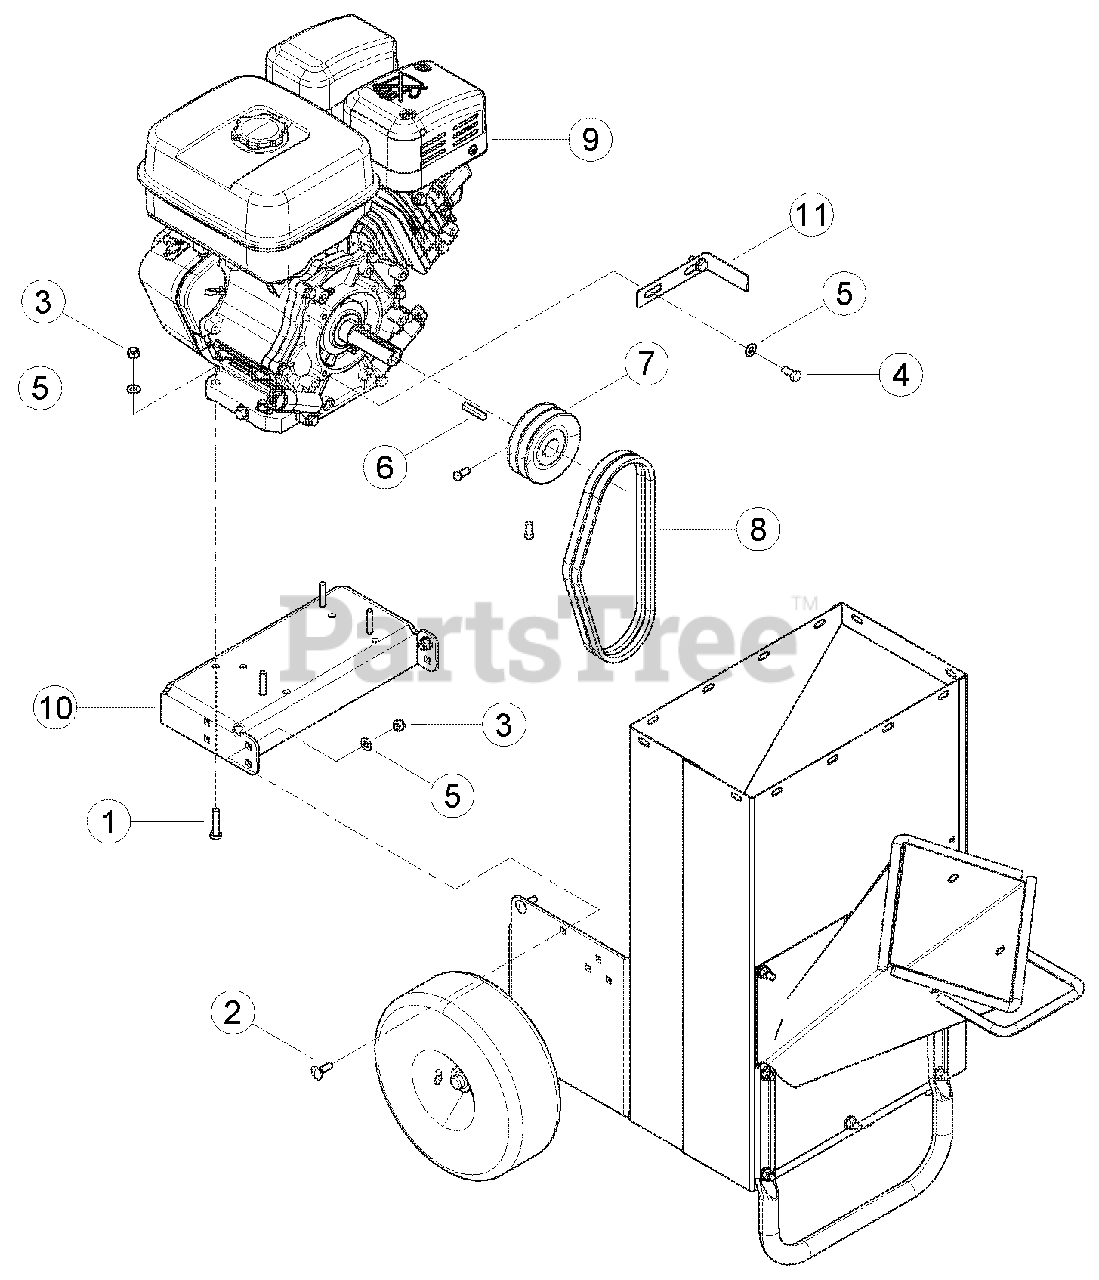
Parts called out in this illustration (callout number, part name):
1	BOLT, 5/16 X 1-1/2 HEX HD GR5 ZP
2	BOLT, 5/16 X 1 CRG GR5 ZP
3	NUT, 5/16 NE NYLOCK ZP
4	BOLT, 5/16-24 X 3/4 HHCS GR5 ZP
5	WASHER, 5/16 SAE FLAT ZP
6	KEY, 1/4 SQUARE X 1-1/2 LONG PLAIN
7	PULLEY, 4X1 2A GROOVE
8	BELTS HAH29.1 EL MATCHED SET
9	ENGINE, SUBARU 265CC HORIZONTAL (FOR SERVICE SEE ENGINE OWNER'S MANUAL OR NEARESTIZED UBARU INDUSTRIAL ENGINE DEALER)
10	PLATE, ENGINE MOUNTING
11	GUIDE, BELT
